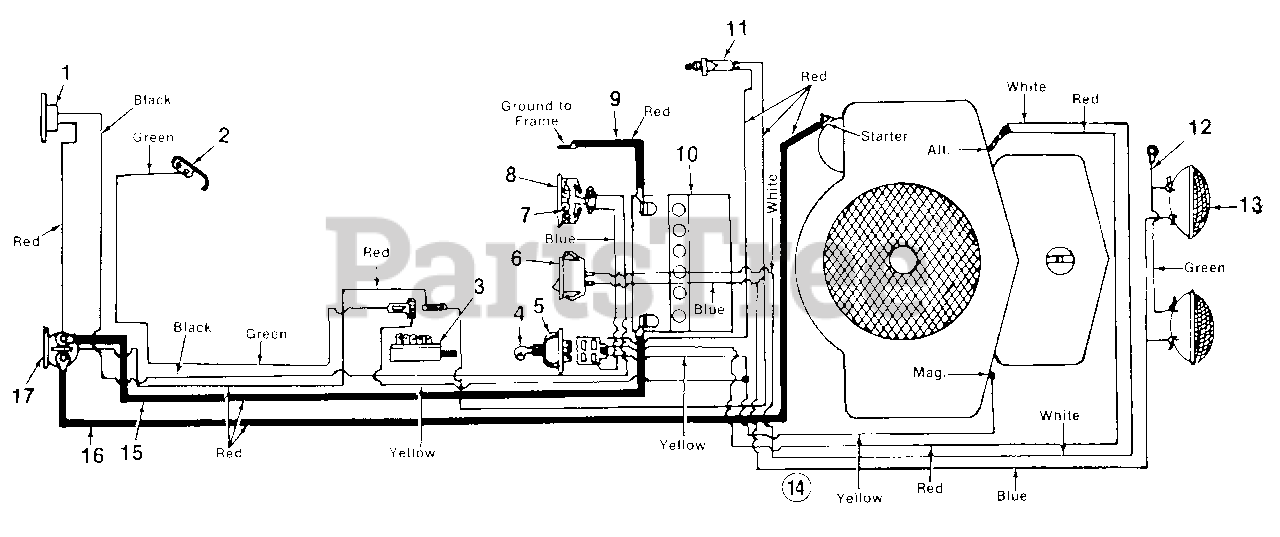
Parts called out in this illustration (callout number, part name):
1	Circuit Breaker
2	Spring Switch
3	Safety Switch Dpst.
4	Ignition Key
5	Ignition Switch
6	Headlight Switch
7	Foam Strip
8	Ammeter
9	Grounding Wire 14.0" Lg.
10	12 Volt Battery
11	Safety Switch
12	Ground Wire
13	Headlight
14	Wire Harness
15	Electric Wire 27.0" Lg.
16	Electric Wire 32.5" Lg.
17	Solenoid
